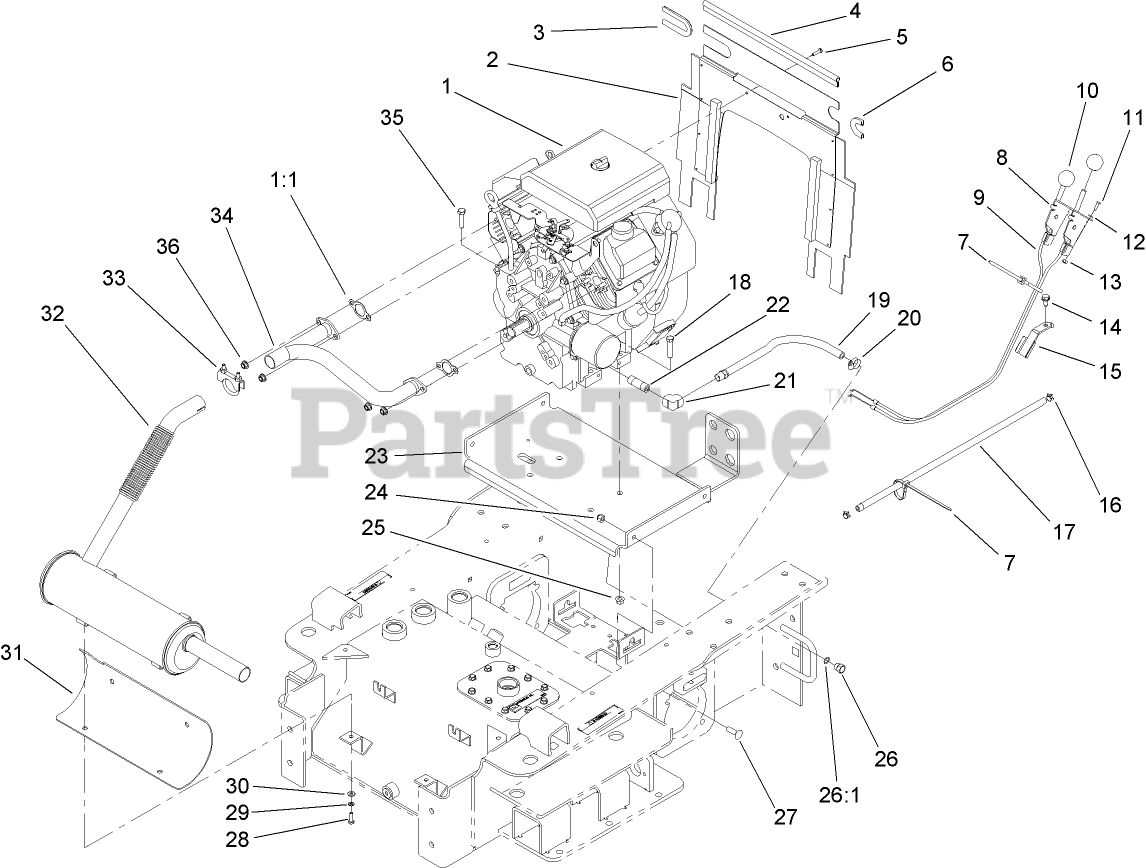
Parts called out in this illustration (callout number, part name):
1:1	GASKET-EXHAUST
2	Engine Baffle ASM
3	SEAL-STRIP, 6.5 INCH
4	Seal-Strip, 16 INCH
5	SCREW-PPH
6	SEAL-STRIP, 3 INCH
7	TIE-CABLE
8	LEVER-CONTROL
9	CABLE-THROTTLE/CHOKE
12	WASHER-FLAT
13	NUT-LOCK, NI
14	SCREW-HWHTF
15	GUIDE-CABLE
16	CLAMP-HOSE
17	HOSE-FUEL
18	SCREW-HH
19	OIL HOSE ASM
20	CLAMP-HOSE
21	ELBOW-90 DEG
22	NIPPLE
23	ENGINE MOUNTING PLATE ASM
24	NUT-LOCK, NI
25	NUT-HF
26	PLUG-HH
26:1	O-RING
27	SCREW-CARR
28	SCREW-HH
29	WASHER-LOCK
30	WASHER-FLAT
31	SHIELD-HEAT, MUFFLER
32	MUFFLER
33	CLAMP-MUFFLER
34	MANIFOLD-CROSSOVER
35	BOLT-HH
36	NUT-HF
